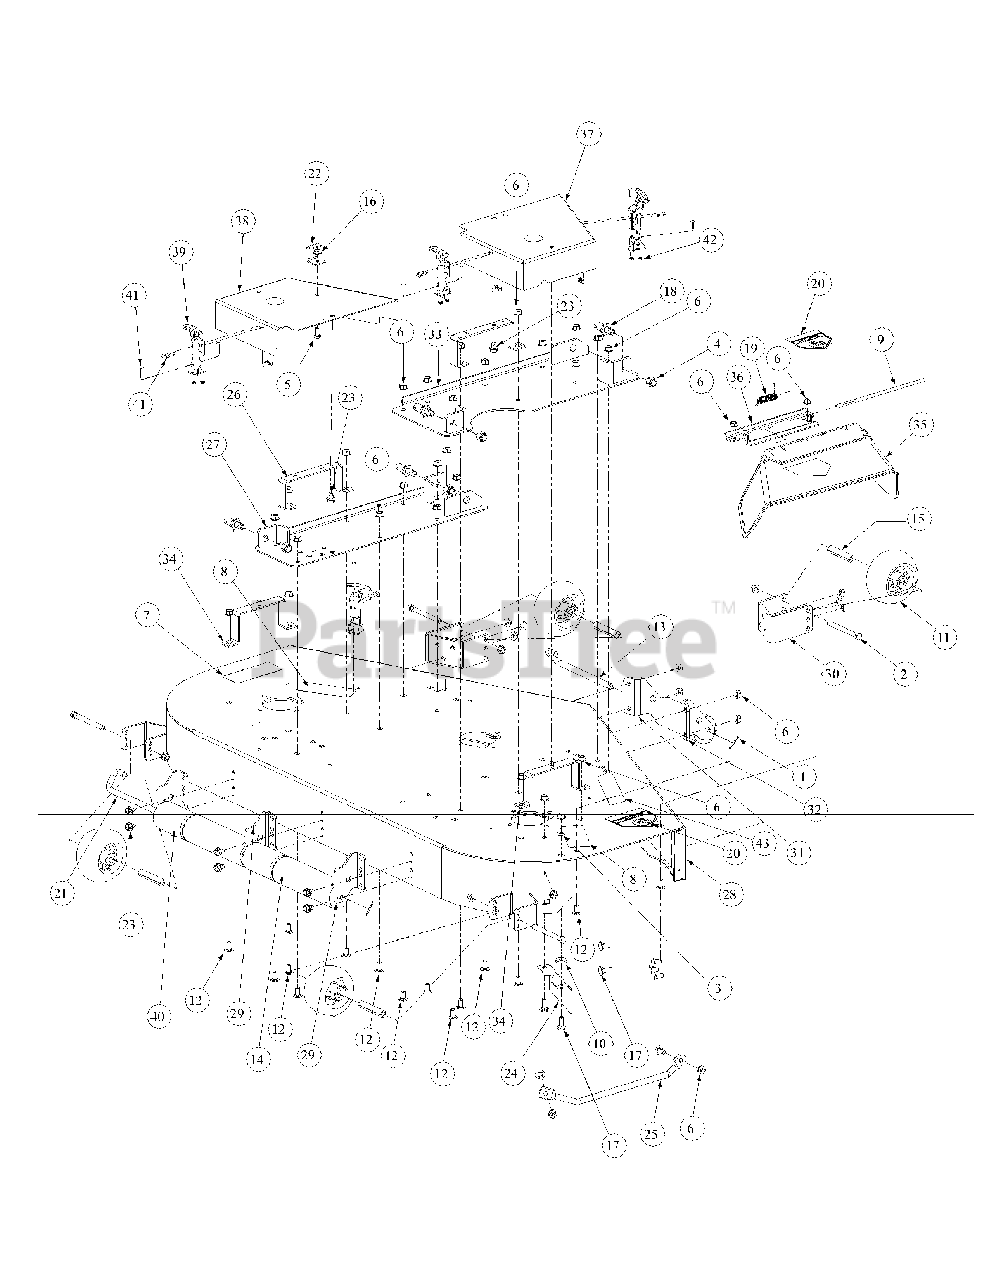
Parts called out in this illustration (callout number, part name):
1	Cotter Pin, .125 Dia. x 1.0
2	Hex Cap Screw, 3/8-16, 3.75
3	Flat Washer, 3/8
4	Lock Nut, Nylon Insert, 1/2-13
5	Hex Cap Screw, 5/16-18 x 3/4
6	Flange Lock Hex Nut, 3/8-16
7	Decal Rotating Blade
8	Decal Warning Shield Missing
9	Chute Deflector Rod
10	Idler Washer
11	Complete Wheel, 5.00 Dia
12	Carriage Bolt, 3/8-16 x .75 Lg
13	Roller Pin, 1/2 Dia x 7.31 Lg
14	Front Roller
15	Wheel Spacer
16	Hex Flange Lock Nut, 5/16-18
17	Carriage Bolt, 3/8-16 x 1
18	Pin, 5/8 Dia. x 1.2 Lg.
19	Torsion Spring, 0.4 ID x 2.16 LG
20	Decal, Danger Hands and Feet
21	Roller Rod
22	Bracket Stop Tension Rod
23	Hex Index Washer Screw, 3/8-16, .05
24	Fabricated Deck, Chute Bracket
25	Fabricated Deck Finger Guard
26	Fabricated Belt Support Cover
27	Left Hand Deck Bracket Assembly
28	48 Fabricated Deck Assembly
29	Fabricted Deck Roller Mount Bracket
30	Front Anti-Scalp Wheel Mount Bracket
33	Right Hand Deck Bracket Assembly
34	Outer Belt Cover Support Assembly
35	Deflector Chute
36	Deflector Chute Bracket
37	Right Hand Belt Cover
38	Left Hand Belt Cover
39	Latch Drawing, T-Handle
41	Phillip Head Screw, 10-32
42	Lock Nut, Nylon Insert, 10-32
43	Commercial Mower Deck Label
